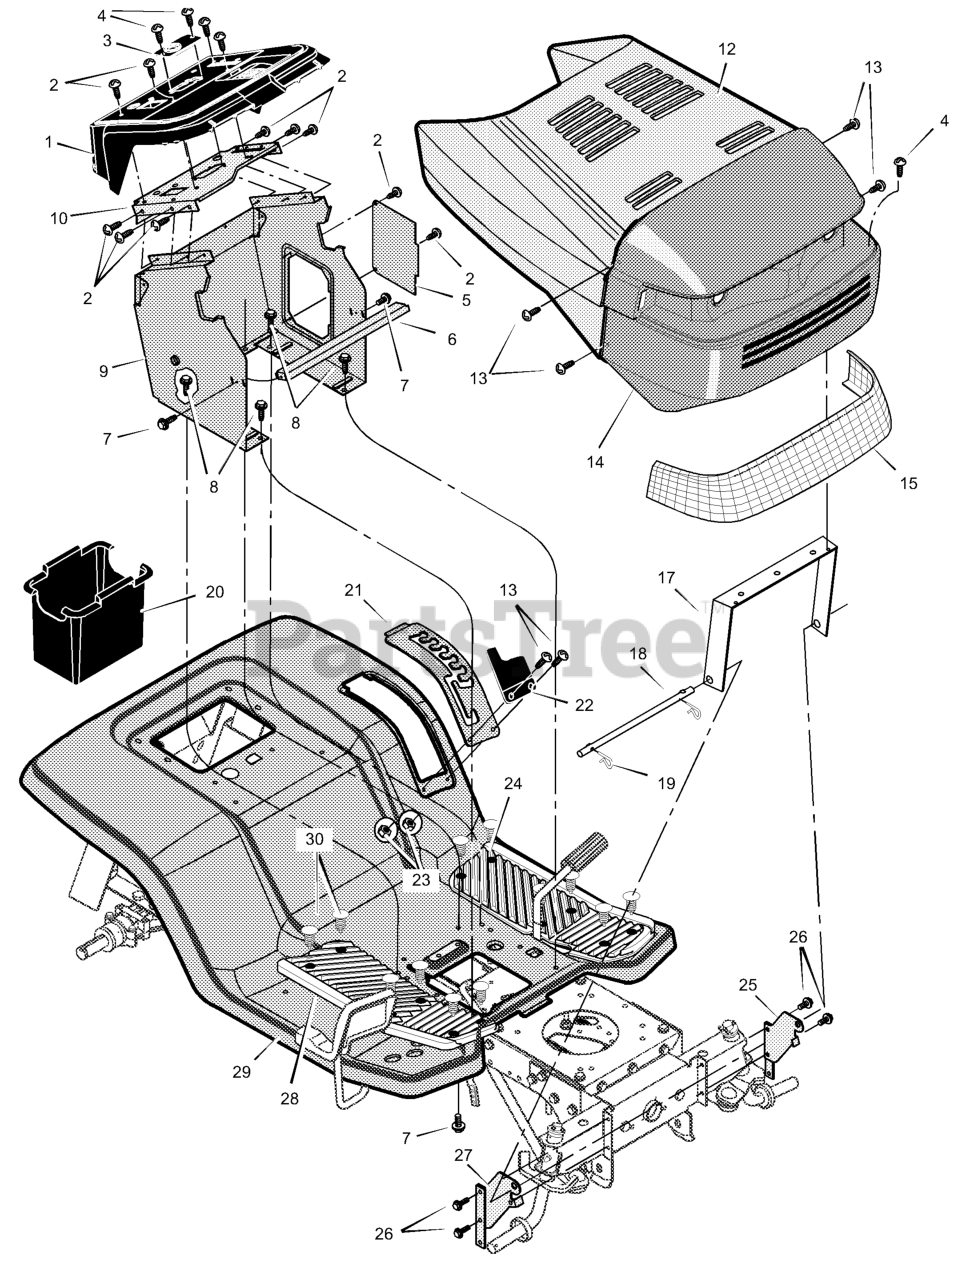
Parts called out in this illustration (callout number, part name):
2	Screw
3	Bearing, Upper Steering
5	Panel, Side Access
6	Channel, Support
9	Support, Dash
10	Plate, Dash
12	Hood
13	Bolt, Shoulder
14	Grille
17	Brace, Grille
18	Rod, Pivot
19	Pin, Hair
20	Container, Battery
21	Plate, Lift Detent
24	Mat, Left
25	Support, Left Grille
27	Support, Right Grille
28	Mat, Right
29	Deck, Seat
30	Fastener
